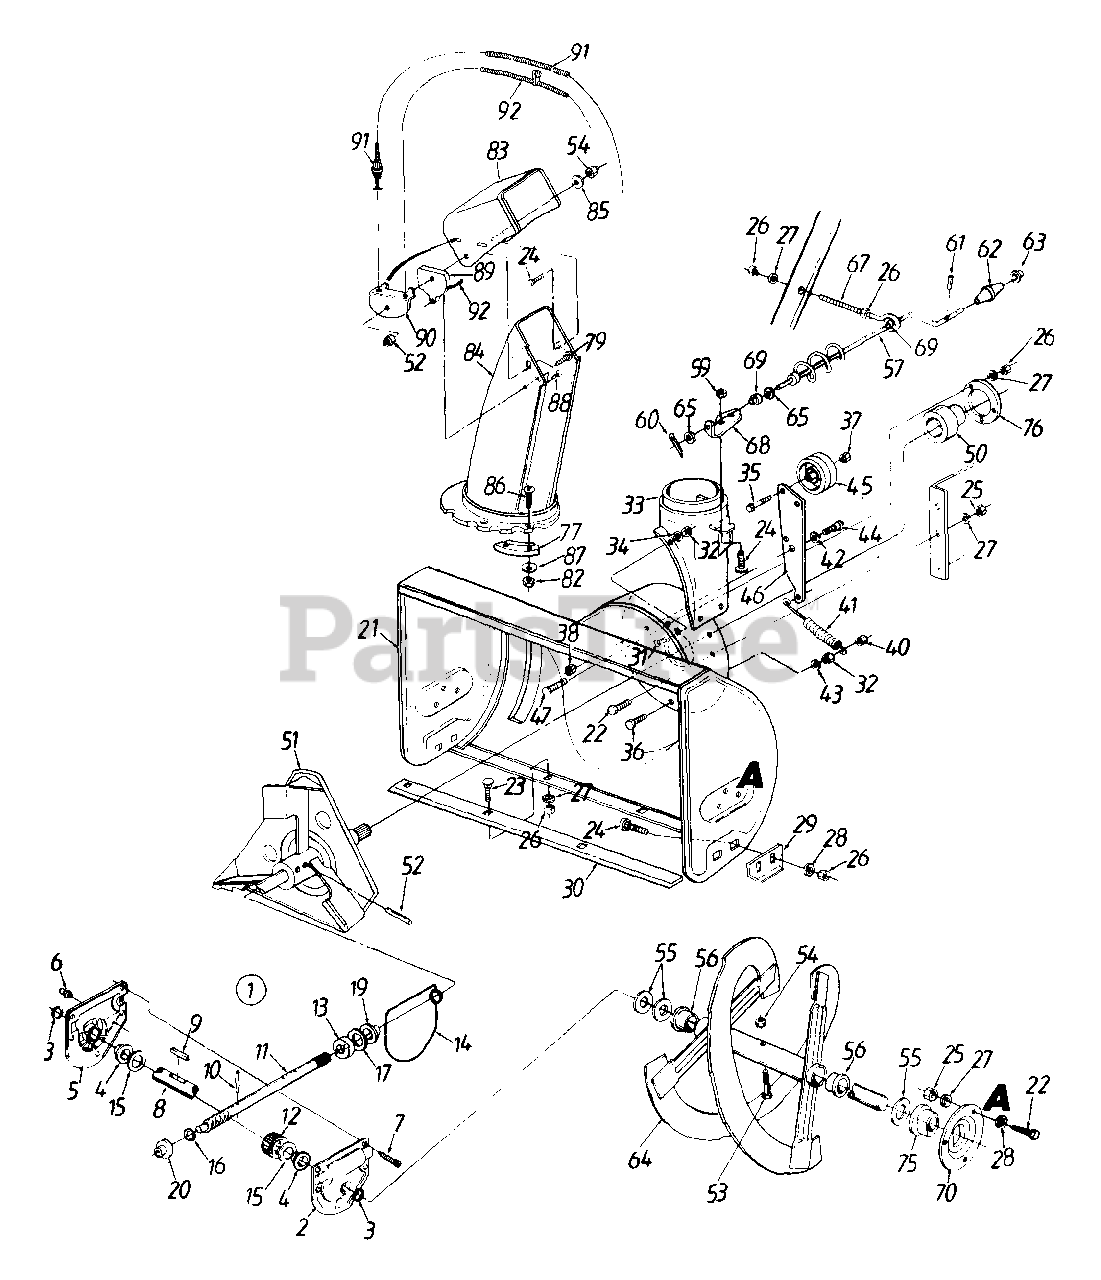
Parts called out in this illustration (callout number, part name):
1	Worm Drive Ass'y. Comp.
2	Reducer Housing - L.H.
3	Oil Seal
4	Flange Bearing .75" I.0.
5	Reducer Housing - R.H.
6	Grease Fitting
7	Hex TT-Tap Scr. 1/4-20 x .75" Lg.
8	24" Auger Shaft
9	#61 Hi-Pro Key 3/16" x 5/8" Dia.
10	Spiral Pin 1.25" Lg.
11	Impeller Shaft
12	Worm Gear
13	Thrust Collar
14	"O"-Ring (Special)
15	Fl-Wash. .76" I.D. x 1.5" O.D.
16	Fl-Wash. .5" I.D. x 1" O.D.
17	Fl-Wash. .76" I.D. x 1.49" O.D.
19	Flange Bearing .75" I.D.
20	Flange Bearing .503" I.D.
21	24" Auger Housing Ass'y.
22	Hex Bolt 5/16-24 x .75" Lg.
23	Carriage Bolt 5/16-18 x .62" Lg.
24	Carriage Bolt 5/16-18 x .75" Lg.
25	Hex Nut 5/16-24 Thd.
26	Hex Nut 5/16-18 Thd.
27	L-Wash. 5/16" I.D.
28	Bell-Wash. .345" I.D. x .88" O.D.
30	24" Shave Plate
31	Truss Mach. Scr. 1/4-20 x .5" Lg.
32	Hex Nut 1/4-20 Thd.
33	Chute Adapter
34	Spring Washer 1/4" I.D.
35	Hex Bolt 3/8-24 x 1.5" Lg. (Gr. 5)
36	Hex Bolt 1/4-20 x .75" Lg. (Gr. 5)
37	Hex Ins. L-Nut 3/8-24 Thd.
38	Hex Top L-Nut 3/8-16 Thd.
40	Hex L-Nut 1/4-20 Thd.
41	Ext. Spring 3.6" Lg.
42	Wave Wash..66" I.D. x .88"
43	L-Wash. 1/4" I.D.
44	Shld. Bolt .625" Dia. x .170" Lg.
45	Fl-Idler 2.75" O.D.
47	Hex Bolt 5/16-18 x 5/8" Lg.
50	Ball Bearing .75" I.D.
51	Blower Fan Ass'y.
52	Spiral Pin 1.5" Lg.
53	Shear Bolt 5/16-18 x 1.5" Lg.
54	Hex Cent. L-Nut 5/16-18 Thd.
55	Fl-Wash. .76" I.D. x 1.49"
56	Flange Bushing .8" I.D.
57	Chute Crank Ass'y.
59	Hex Ins. L-Nut 5/16-18 Thd.
60	Cotter Pin 3/32" Dia. x .75"
61	Roll Pin 1/8" Dia. x .63" Lg.
62	Chute Crank Knob
63	Push Nut
65	Fl-Wash. .385" I.D. x .62" O.D.
67	Eye Bolt 5/16-18 x 3" Lg.
69	Plastic Bushing .38" I.D.
75	Plastic Bearing w/Flats
76	Bearing Housing
77	Chute Flange Keeper
79	Carriage Bolt 5/16-18 x 1.5" Lg.
82	Hex L-Nut 1/4-20 Thd.
83	Upper Chute
84	Lower Chute
85	Fl-Wash. .344" I.D. x 1.125"
86	Truss Mach. Scr. 1/4-20 x .75" Lg.
87	Fl-Wash. 1/4" I.D.
88	Hex AB-Tap Scr. 1/4 x .62" Lg.
89	Cable Guide
91	Chute Control Cable
92	Chute Control Cable w/Clip
